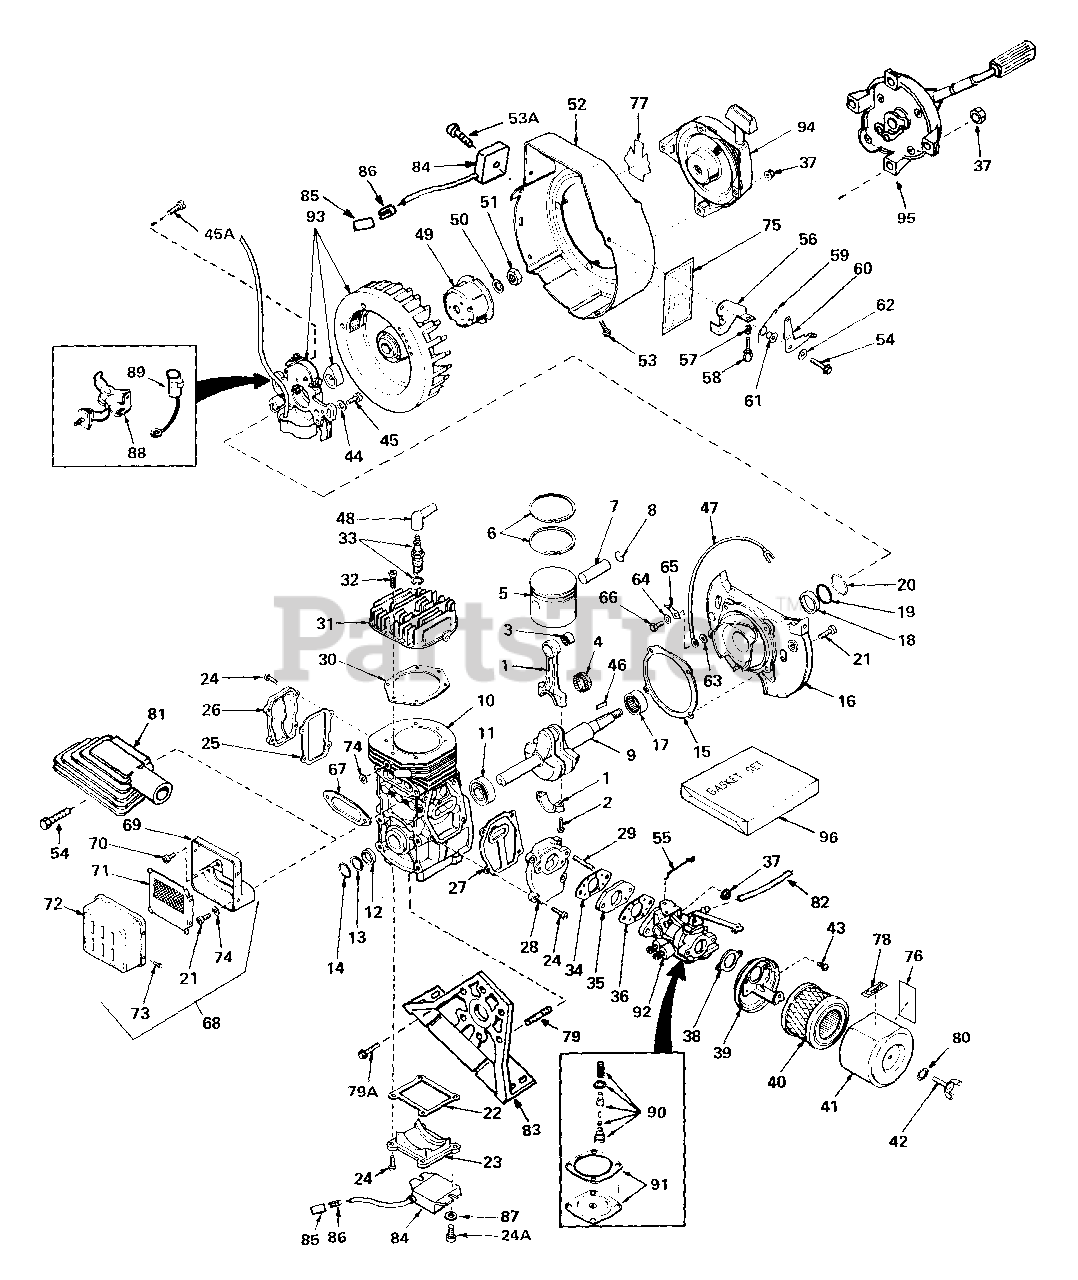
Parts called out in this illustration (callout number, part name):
1	"Rod Assy., Connecting
2	Screw, Connecting rod
3	Bearing, Cartridge
4	Bearing Set, Needle
5	Piston
6	Ring Set, Piston
7	Pin, Piston
8	Ring, Piston pin retaining
9	Crankshaft
10	Cylinder Assy.
11	Bearing, Ball
12	Sea], Crankshaft
13	Retainer, Seal
14	Spring, Retainer
15	Gasket
16	Base Assy., Housing
17	Bearing, Cartridge
18	Seal, Crankshaft
19	Retainer, Seal
20	Spring, Retainer
21	Screw
22	Gasket, Cover plate
23	Plate, Cover
25	Gasket, Cover plate
26	Plate, Cover
27	Gasket, Adapter cover
28	Cover, Adapter
29	Stud, Carburetor
30	Gasket, Cylinder head
31	Head, Cylinder
33	Plug, Spark (Champion J 13Y or equiv alent)
34	Gasket
36	Gasket, Carburetor
37	Nut
38	Gasket
39	Base, Air cleaner
40	Cleaner, Air
41	Cover, Air cleaner
42	Screw, Thumb
46	Key, Flywheel
47	Wire, Ground
48	Cover, Spark plug
49	Cup, Starter
52	Housing, Blower
55	Link, Throttle
56	Bracket, Speed control
58	Screw, Speed adjusting
59	Spring, Torsion
60	Lever, Speed control
61	Bushing
62	Washer
63	Washer, Nylon flat
64	Washer, Nylon shoulder
65	Clip, Terminal
66	Screw
67	Gasket, Exhaust
75	Decal, Operating instruction
76	Decal, Air cleaner
77	Decal, Identification
78	Decal, Choke
80	Lockwasher, No. IO E.T.
81	Adapter, Muffler
88	Contact Assy., Breaker
89	Condenser
90	Inlet Needle, Seat & Gasket Assy.
91	Diaphragm Assy.
92	Carburetor
93	Magneto
94	Starter, Rewind
96	Gasket Set (Incl. items marked*)
